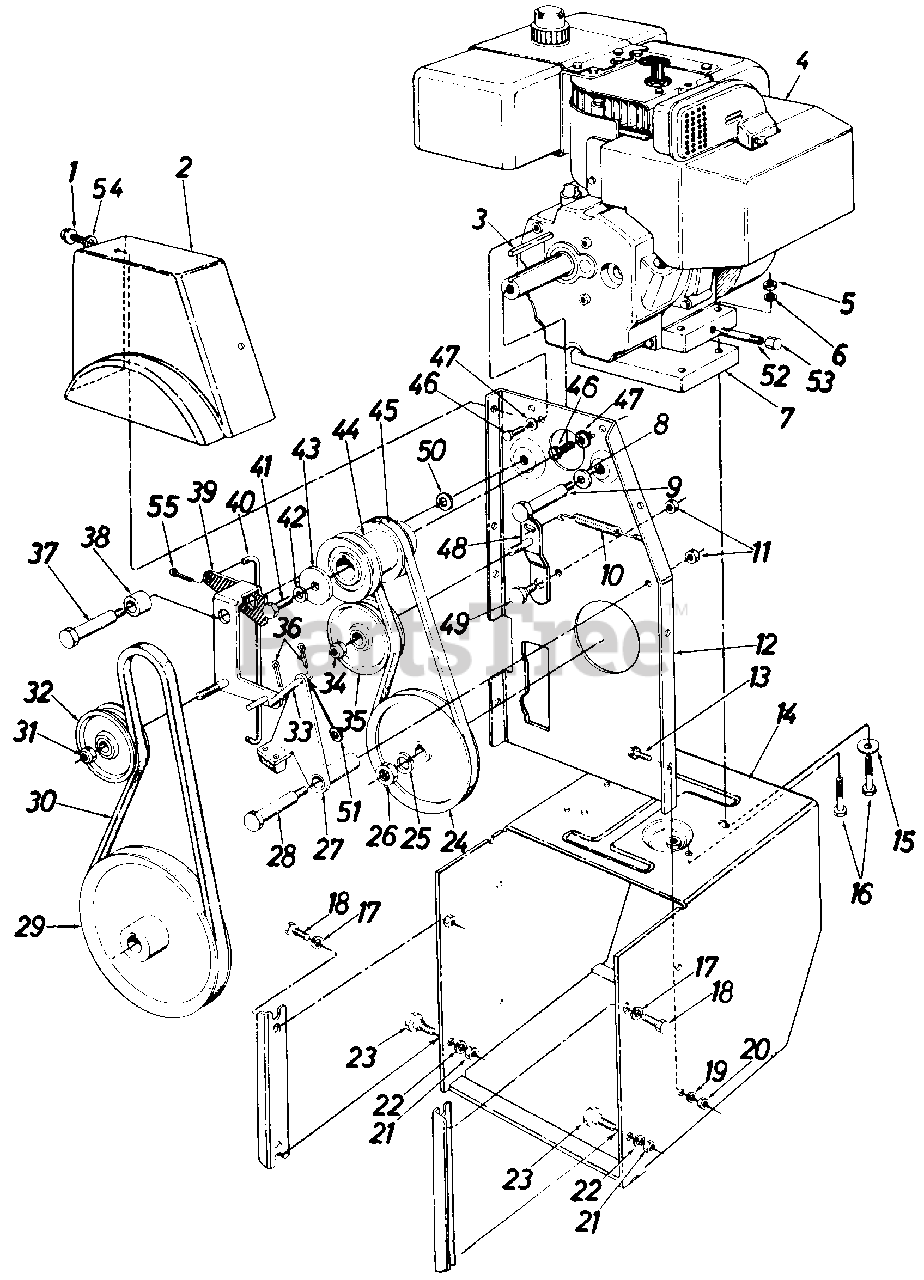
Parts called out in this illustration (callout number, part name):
1	Hex AB-Tap Scr. 5/16 x .75" Lg.
2	Belt Cover
3	Sq. Key 1/4" X 1.50" Lg.
4	Engine
5	Hex Nut 5/16-18 Thd.
6	L-Wash. 5116" I.D.*
7	Engine Spacer Ass'y.
8	Bell-Wash. .40 I.D. x .88 O.D.
9	Shld. Bolt .498" Dia. x 3.00" Lg.
10	Ext. Spring .38 O.D. x 3.18" Lg.
11	Hex Cent. L-Nut 3/8-16 Thd.
12	Engine Brkt. Ass'y.
13	Hex Sems Scr. 5/16-18 x .75" Lg.*
14	Frame Ass'y.
15	Fl-Wash. .345 I.D. x .75 O.D. x .060
16	Hex Bolt 5/16-18 x 2.50" Lg.
17	L-Wash. 318" I.D. H.D.
18	Pilot Scr. 3/8-16 x .88" Lg.
19	L-Wash. 5/16" I.D.
20	Hex Nut 5/16-18 Thd.
21	Hex Nut 3/8-16 Thd.*
22	L-Wash. 3/8" I.D. H.D.
23	Shld. Bolt .498" Dia. x .340" Lg.
24	V-Pulley .628 I.D. x 7.50 O.D.
25	L-Wash. for 5/8" I.D.*
26	Hex Ins. Jam L-Nut 5/8-18 Thd.
27	Brake Brkt. Ass'y.
28	Shld. Bolt .498" Dia. x 2.00" Lg.
29	V-Pulley .875 I.D. x 10.12 O.D.
30	V-Belt
31	Hex Ins. Jam L-Nut 3/8-24 Thd.
32	Fl-ldler w/Flanges 3.0 O.D.
33	Brake Linkage Ass'y.
34	Hex Ins. Jam L-Nut 3/8-24 Thd.
35	3.0" O.D. Fl-ldler w/Flanges
36	Int. Cot. Pin 3/32" Dia.
37	Shld. Bolt .625" Dia. x 2.750" Lg.
38	Spacer .75 O.D. x 1.00" Lg.
41	Hex Bolt 3/8-24 x 1.25" Lg.
42	L-Wash. 3/8" I.D. H.D.
43	Fl-Wash.
44	Engine Pulley-Double Groove
45	V-Belt
46	Hex Bolt 5/16-24 x .62" Lg.
47	Bell-Wash. .345 I.D. x .88 0 O.D. x .060
48	Drive Idler Brkt. Ass'y.
49	Shld. Bolt-.625" Dia. x .170" Lg.
50	Bell-Wash. .40 I.D. x 1.12 O.D.
51	Fl-Wash. .385" I.D. x .620" O.D.
52	Pipe Nipple-1/4" Pipe Thd. x 3.5" Lg.
53	Hex Hd. Cap 1/4-18 Pipe Thd.
54	Fl-Wash. .340 I.D. x .62 O.D. x .62
55	Int. Cot. Pin 5/16" Dia.
